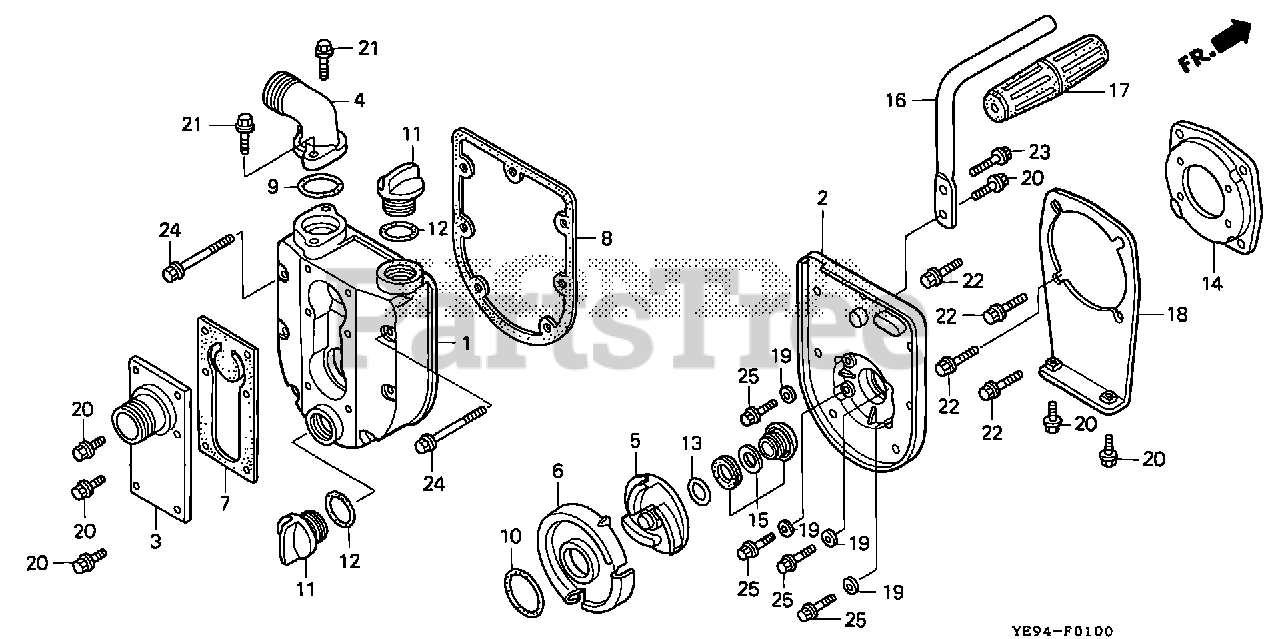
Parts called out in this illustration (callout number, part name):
1	CASING
2	PLATE, END
3	PLATE, SUCTION
4	PIPE, OUTLET
5	IMPELLER
6	CASE, VOLUTE
7	GASKET, SUCTION
8	GASKET, END PLATE
9	O-RING
10	RING A, SEAL
11	CAP, FILLER
12	RING, SEAL (B)
13	SHIM, ADJUSTER
14	CASE, SPACER
15	SEAL ASSY., MECHANICAL
16	HANDLE
17	GRIP, FR. CLUTCH LEVER
18	BRACKET, PUMP
19	WASHER, SEALING (6MM)
20	BOLT, FLANGE (6X14)
21	BOLT, FLANGE (6X18)
22	BOLT, FLANGE (6X20)
23	BOLT, FLANGE (6X25)
24	BOLT, FLANGE (6X55)
25	BOLT, FLANGE (6X18)
